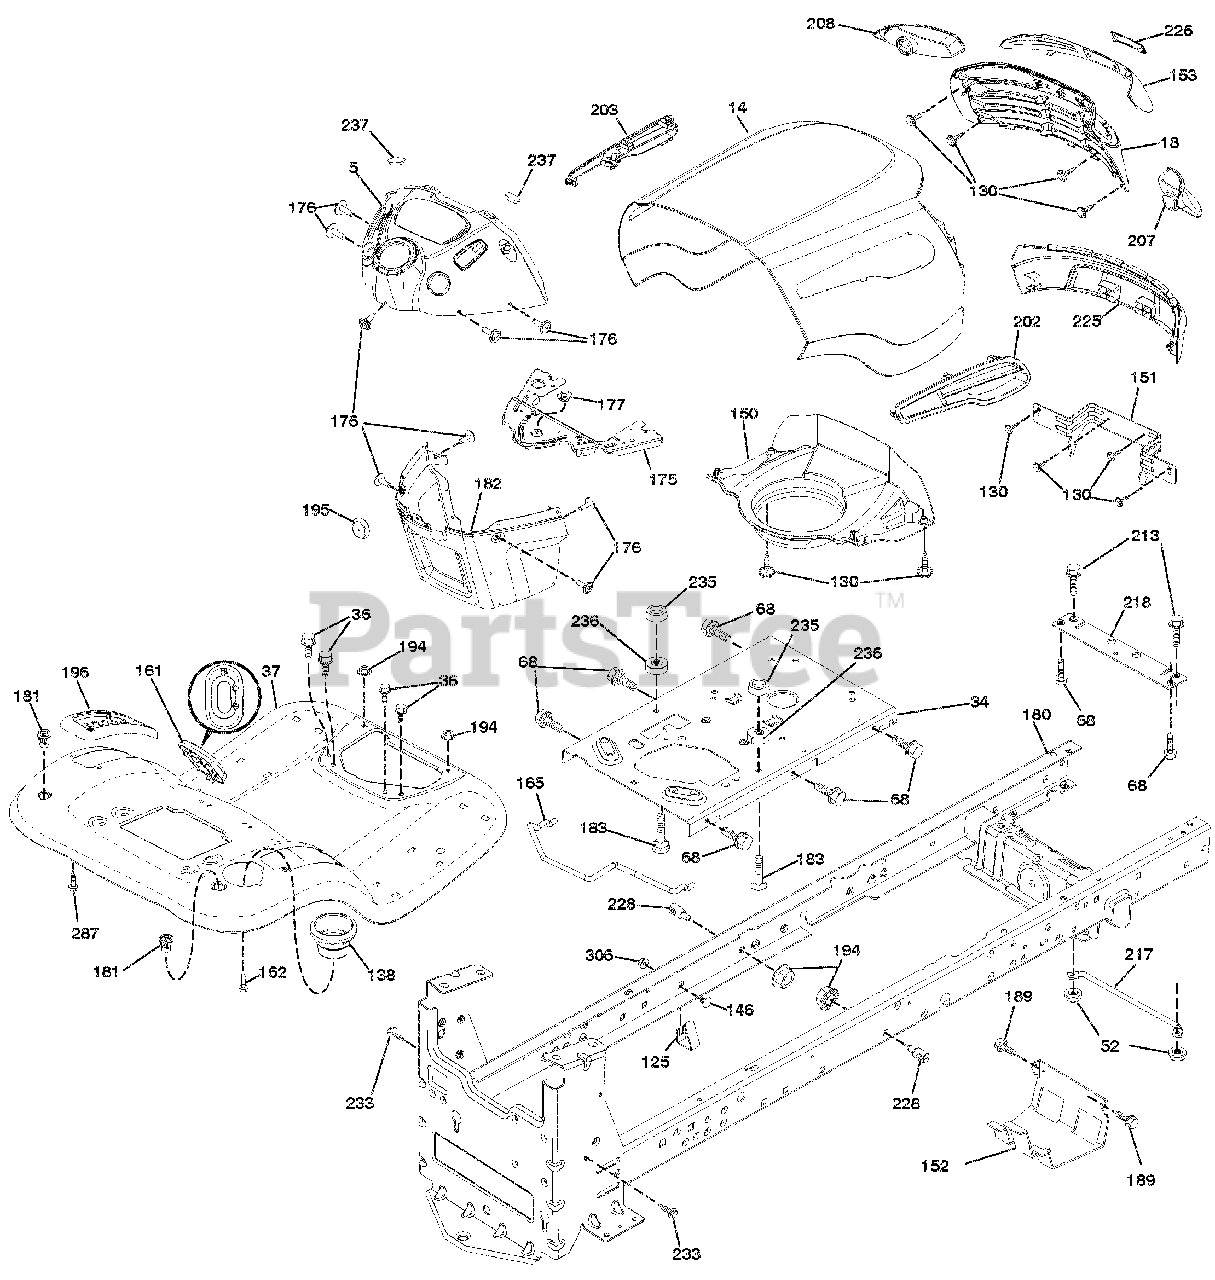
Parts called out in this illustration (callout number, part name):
5	DASH P/L TEX CABLE
18	GRILLE.ELITE.ARIENS.BLACK
34	PLATE.ENGINE.WELDED.CHASSIS
36	SCREW.5/16-18X3/4.SMGML.TAP/R
52	Nut, Hex, Crownlock 5/16-18
68	SCREW.THDROL.5/16-18 X 1/2TYTT
125	CLIP.FUEL.LINE
138	CUPHOLDER TL TEX 428
150	AIR DUCT
151	BRACKET.PIVOT
152	SHIELD.BROWNING.W/TEX
153	LENS.BAR
161	WINDOW FUEL
162	SCREW.HEX.WSH.HI-LO.1/4X1/2UNC
165	SUPPORT.TANK.REAR.W/TEX
175	CROSSMEMBER.LT
176	SCREW.#10-24X5/8.RND.QUDRX.GIM
177	BUSHING.STEERING.LT
180	CHASS WLDMT TL 12 GA/2PC 18/22
181	BUSHING MNT FEND CRGO BLK TEX
182	DASH.LOWER.LT.CCS
183	BOLT.FIN.HEX.5/16-18 UNC X1-1/
189	SCREW.5/16-18X3/4.SMGML.TAP/BL
194	Nut, Lock Hex Flange 5/16-18 u
195	PLUG HOLE DASH TOWER
196	CONSLE.ASM.DECK.LFT.BL/RBT.TLT
202	VENT RH
203	VENT.SIDE.LH
207	BEZEL.RH
208	BEZEL.LH
213	BOLT.HEX.HD.1/4-20UNC X 3/4
217	ROD.PIVOT.HOOD
218	X-PIECE.HOOD.STOP.NON/STEALTH
226	ARIENS.LOGO.PLATE
228	STUD.FASTNER.W/'D'ANTI-ROTATIO
233	BOLT.SHOULDER
235	SPACER.FENDER
236	NUT.CENTER LOCK.5/16-18 UNC
237	PLUG.MOUNT.CARGO
287	SCREW.HEX.WASHEAD.1/4-20 X 3/8
306	Nut, Hex, Flangelock 3/8-16
